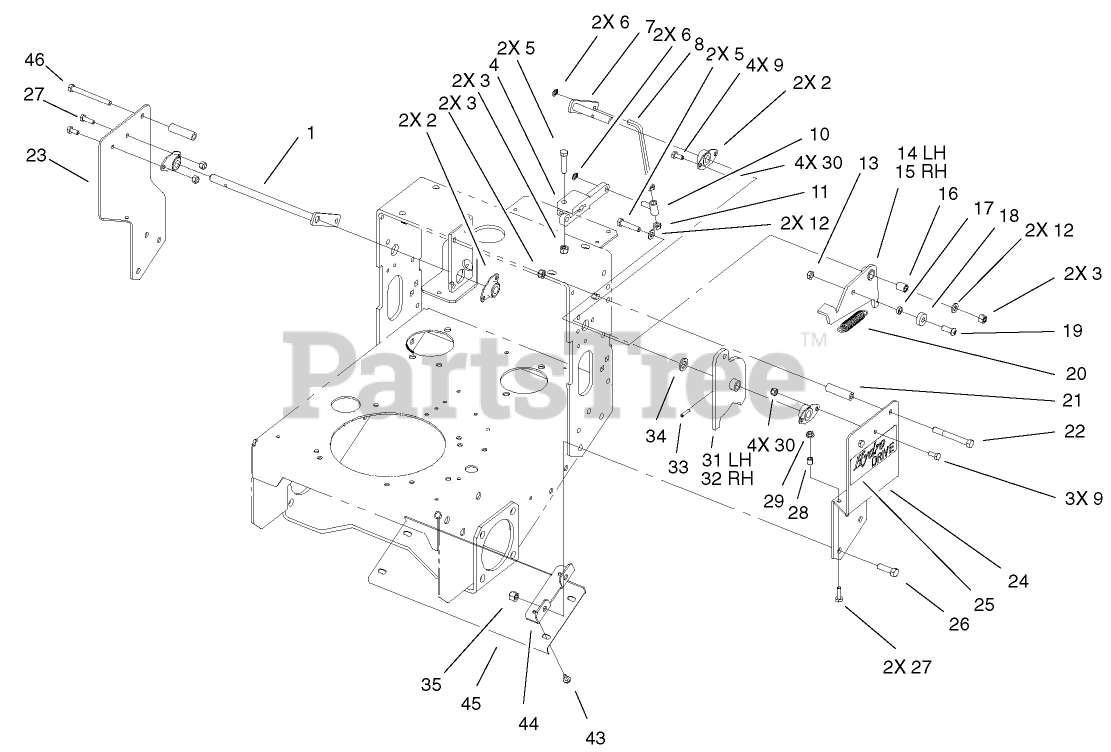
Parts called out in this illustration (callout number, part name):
1	LEVER-PIVOT, RH
2	SIDE FLANGE BEARING ASM
3	NUT-LOCK, NI
4	ARM-PUMP
5	SCREW-HH
6	RING-GRIP
7	LEVER-PIVOT, LH
8	ROD-LINK
9	SCREW-HH
10	SLEEVE
11	NUT-JAM
12	WASHER-PLAIN
13	NUT-LOCK, NI
14	ARM-DETENT, LH
15	ARM-DETENT, RH
16	BUSHING-ARM, DETENT
17	SPACER-BEARING
18	BEARING-BALL
19	SCREW-HSBH
20	SPRING-EXTENSION
21	STOP-REVERSE
22	SCREW-HH
23	BRACKET-PIVOT, LEFT
24	BRACKET-PIVOT, RIGHT
25	DECAL-HYDRO
26	SCREW-HH
27	SCREW-HH
28	SPACER-TUBULAR
29	NUT-LOCK, HHF
30	NUT-LOCK, NI
31	ARM-PIVOT, LH
32	ARM-PIVOT, RH
33	PIN-ROLL, SLOTTED
34	WASHER-THRUST
35	NUT-LOCK, NI
43	SCREW
44	Angle-Mounting
45	Panel-Bottom
46	SCREW-HH
